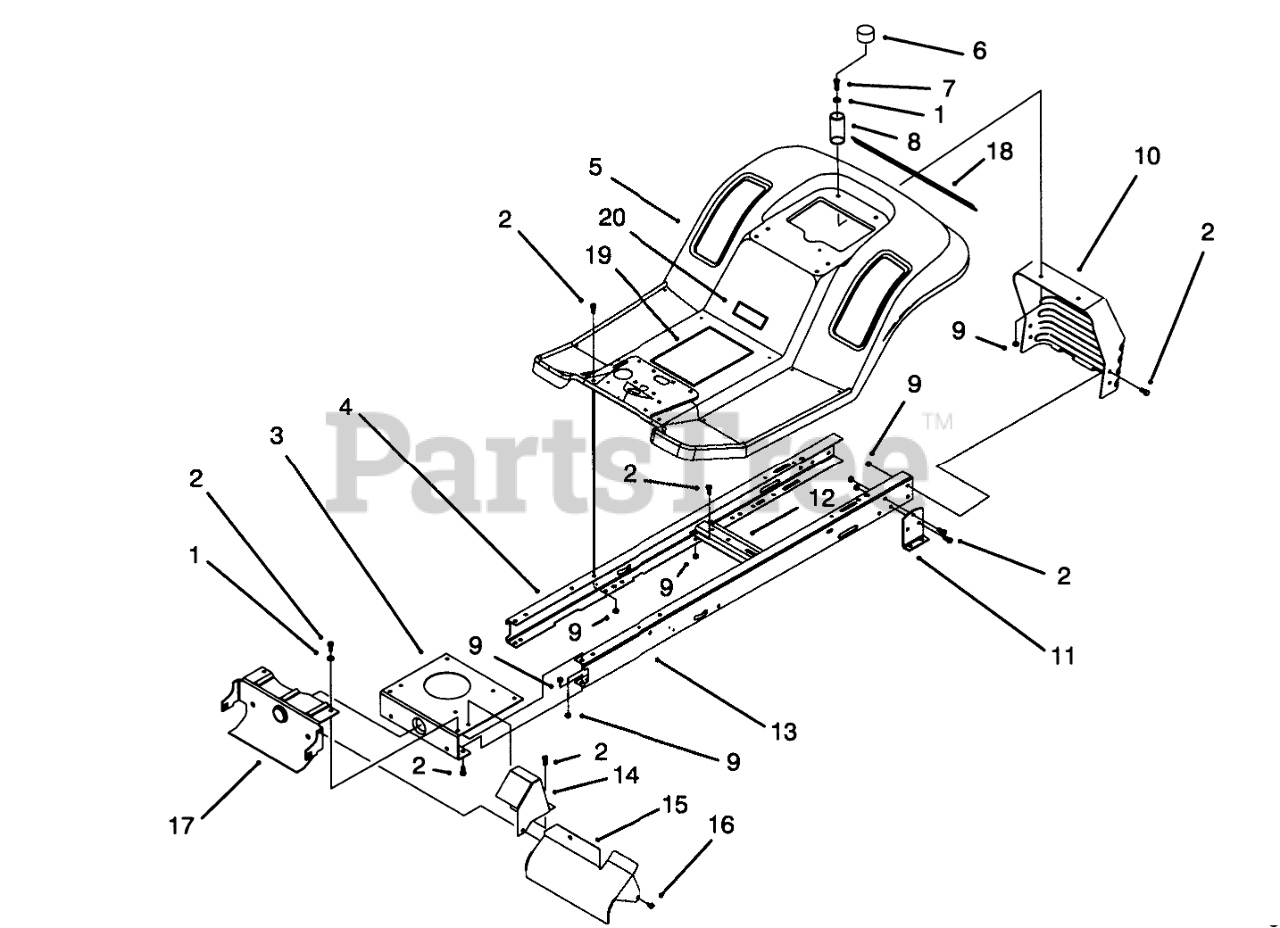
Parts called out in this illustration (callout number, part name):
1	WASHER-PLAIN
2	SCREW-HH
3	Plate-Engine Mount
4	Frame-Rail R.H.
5	BODY-REAR
6	CAP-PROTECTOR
7	SCREW-HH
8	SPRING-COMPRESSION
9	NUT-LOCK, NI
10	Panel-Rear Hitch
11	Bracket-Transaxle
12	Bracket-Idle Pivot
13	Frame-Rail L.H.
14	Shield-Exhaust Pipe
15	Shield-Muffler
16	SCREW-HWHTF
17	Support-FrontAxle
18	DECAL - REAR BODY
19	Decal-Instruction
20	Decal-Made In USA
